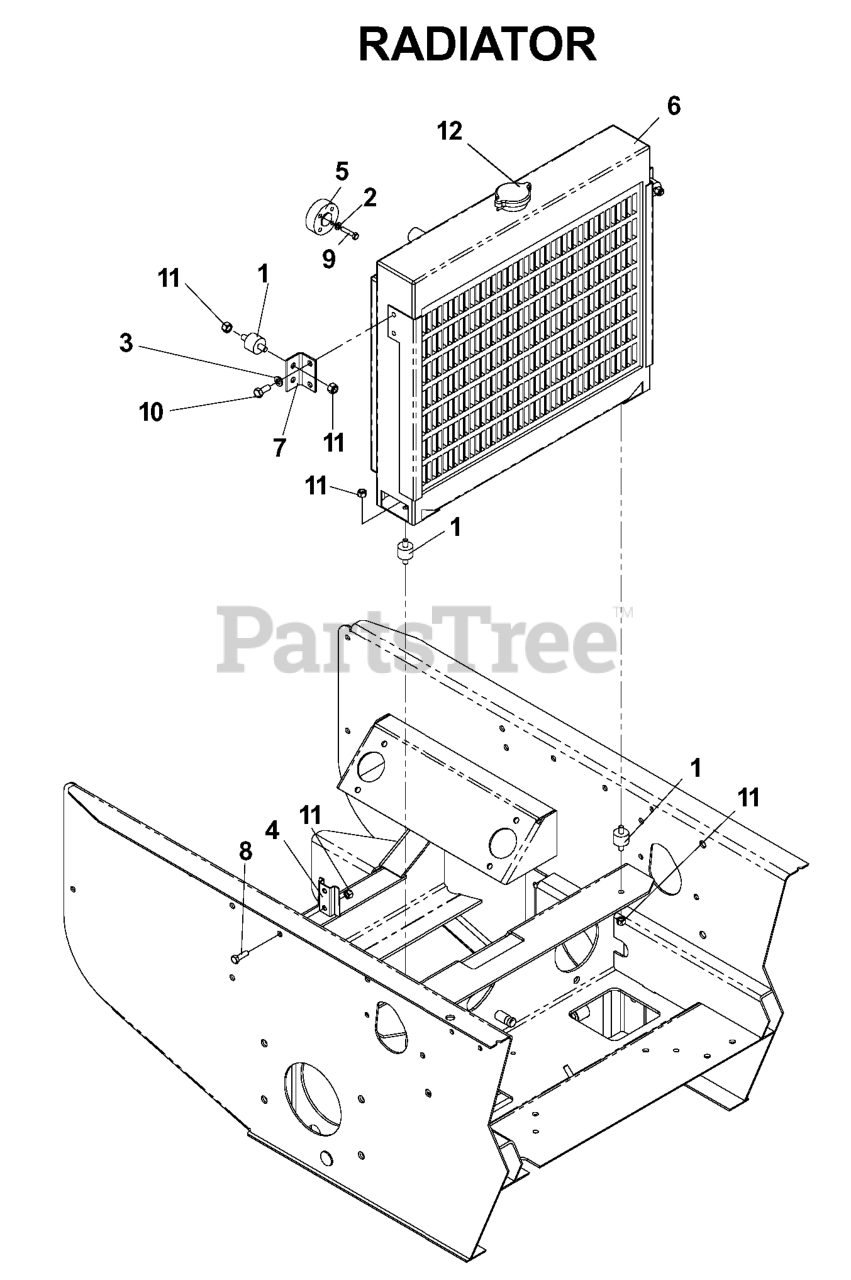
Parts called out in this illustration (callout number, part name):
2	LOCKWASHER 1/4"
3	WASHER.LOCK.HVY.HLCL.SPR.5/16
4	MOUNTING BRACKET
5	SPACER FAN
6	RADIATOR ASSY
7	BRACKET ISO
8	HCS 5/16C X 1
10	HCS 5/16C X 3/4
11	NUT 5/16 NYLOC
539106326	LOWER HOSE
539106402	OVERFLOW TANK ASM
